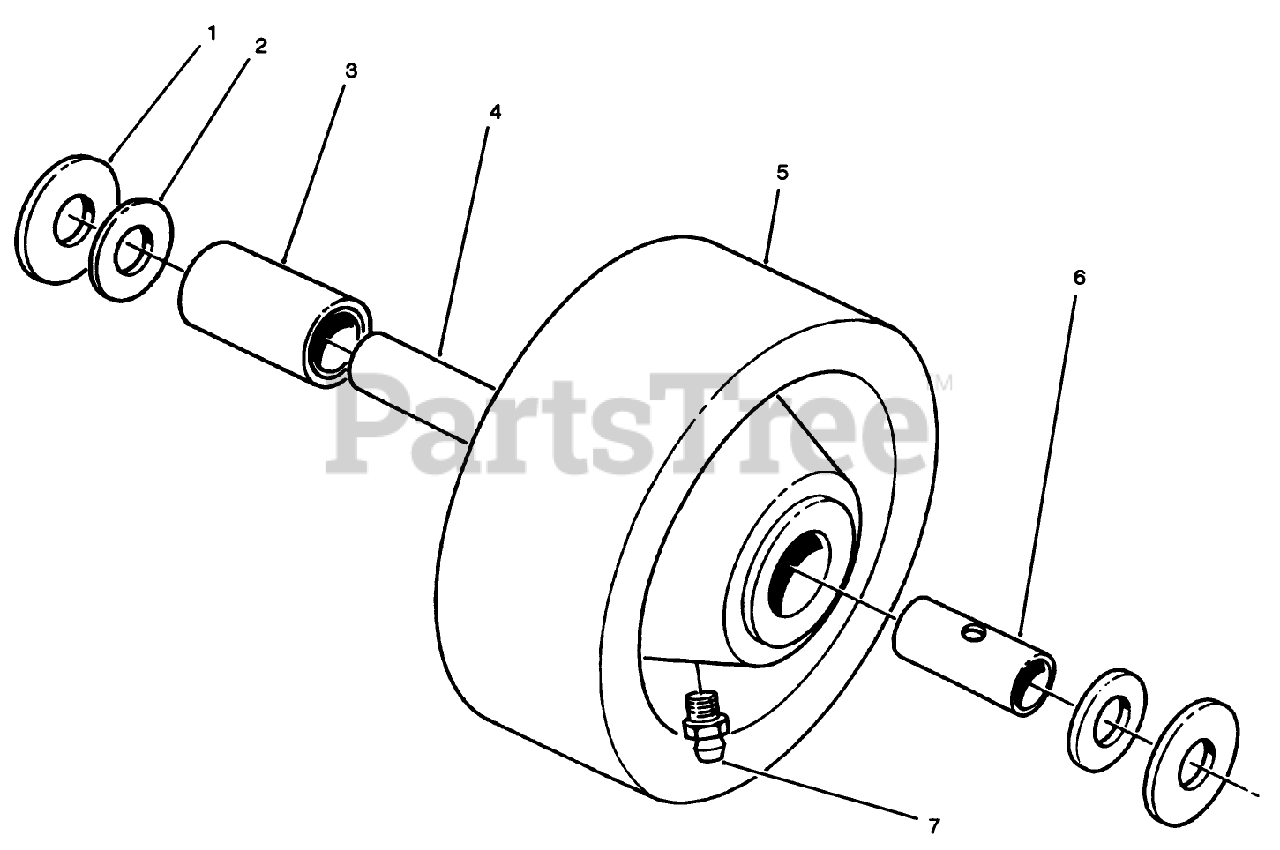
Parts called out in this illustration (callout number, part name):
1	THRUST WASHER
2	BEARING RETAINER
3	ROLLER BEARING
4	SPANNER-TIRE
5	WHEEL
6	SPANNER BUSHING
7	FITTING-GREASE
